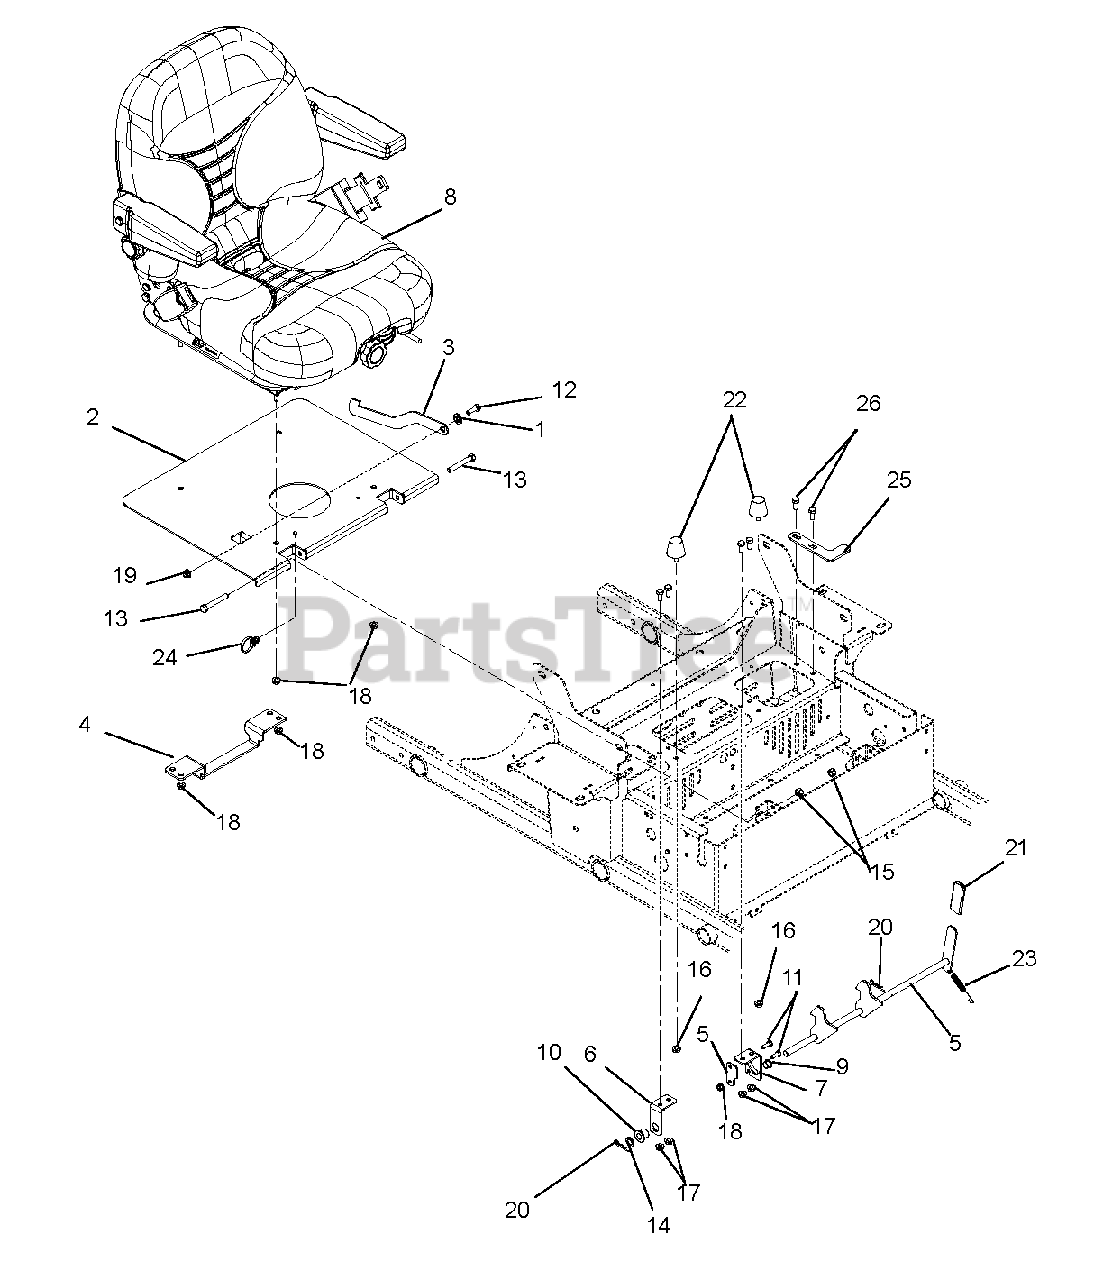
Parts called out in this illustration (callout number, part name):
1	Bushing, Flange .325 x .499 x .26 x .88
2	Seat Plate Weldment - Black
3	Stop, Seat Pivot
4	Bracket - Seat Latch
5	Weldment - Seat Latch
6	Mount - Seat Latch -RH
7	Mount - Seat Latch -LH
8	Seat, SUSP, w/Seat Belt, LT GRY
9	Bushing, Polyliner -.50 Split
10	Bushing, Flange .515 x .750 x .745 x 1.00NY
11	Bolt, Hex .25-20 x .75 GR5 YWZC
12	Bolt, Hex .31-18 x .75 GR5 YWZC
13	Bolt, Hex .38-16 x 2.50 GR5 YWZC
14	Washer, Flat Steel .52 x .827 x .062 YWZC
15	Nut, Locking Center .38-16 YWZC
16	Nut, Spin Lock-Flange .312-18 YWZC
17	Nut, Locking Top-Flange .31-18 YWZC
18	Nut, Locking Top-Flange .25-20 YWZC
19	Nut, Locking Nylon-Flange .31-18 YWZC
20	Pin-Hair-Internal .08 x .38 x 1.42 YWZC
22	Bumper, Rubber Cone, Stud Mount
23	Spring, Tension .043 x .44 x 3.31 WLD 5.8
24	Cable Tie with Tree (.25 HOLE)
25	Bracket, CE Seat Locking
26	Screw, Tapping .25-20 x .50 Hex Washer Head
